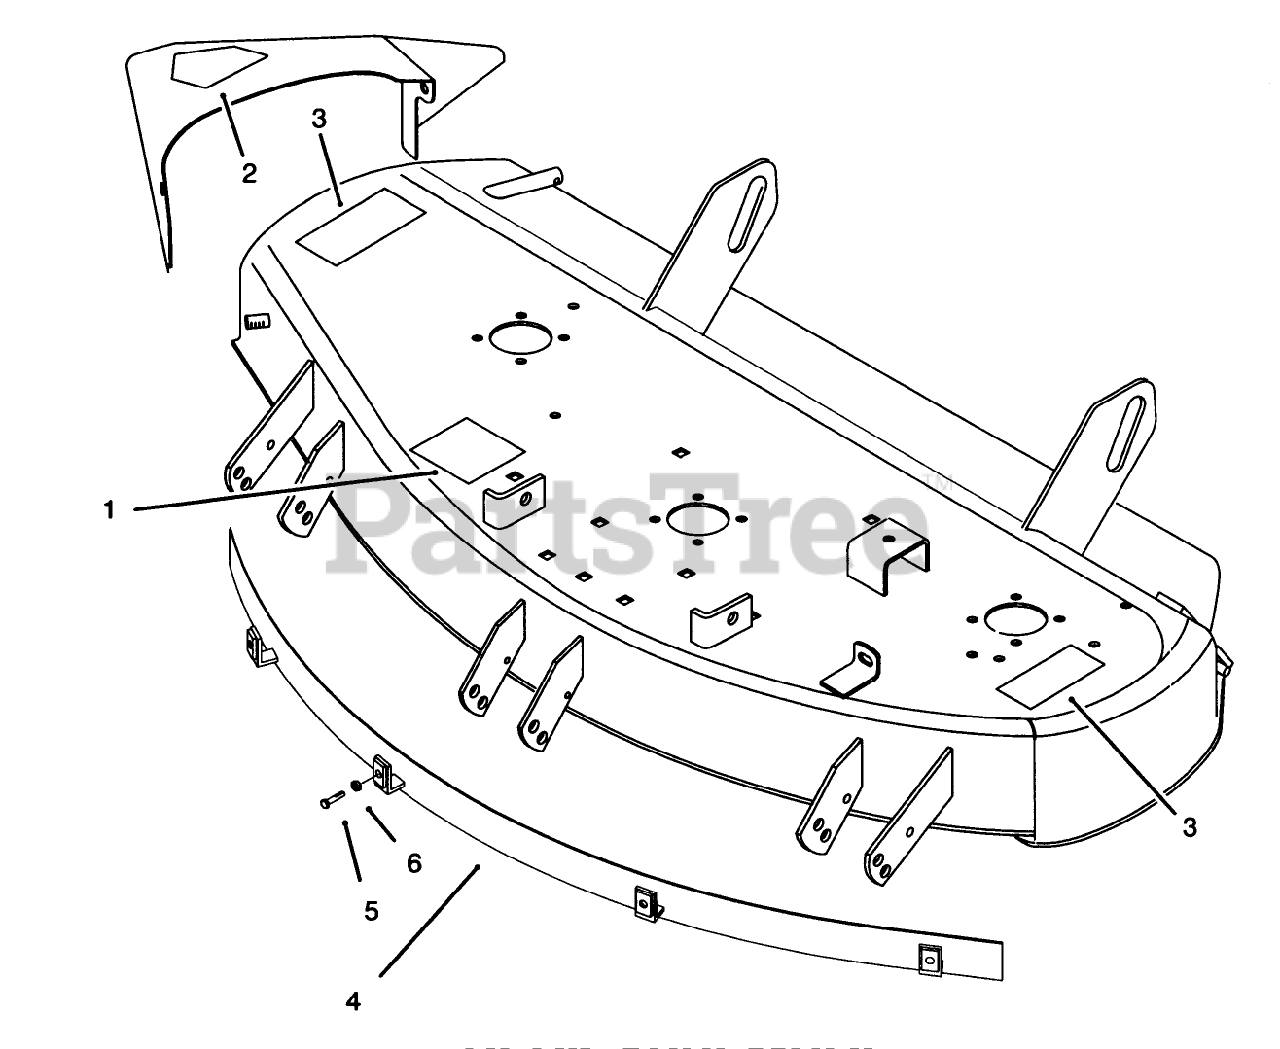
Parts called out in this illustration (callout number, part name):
1	DECAL - BELT INSTALLATION
2	DECAL-DANGER
3	DECAL-DANGER
4	WA-FRONT SHIELDR
5	Screw-Hex Hd.
6	NUT-JAM
